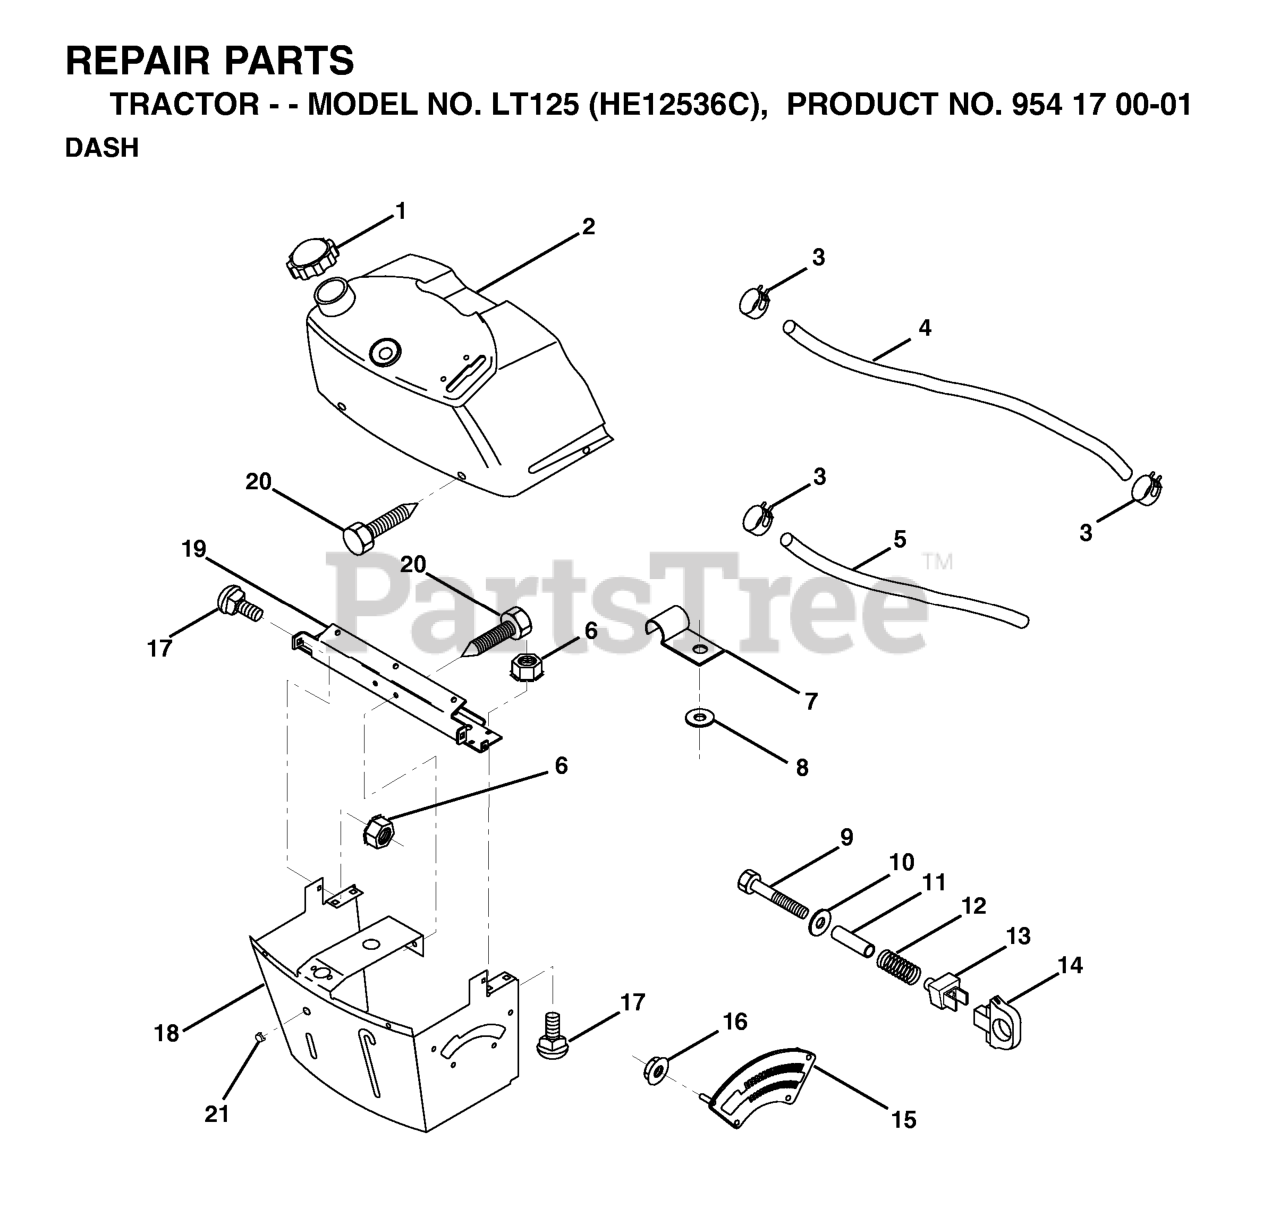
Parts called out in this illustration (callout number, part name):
1	CAP.FUEL.GREY
2	TANK ASM DASH LR
3	HOSE CLAMP
4	FUEL LINE
5	FUEL LINE T
6	Nut, Keps Blk Hex 1/4-20 UNC
7	CLIP T
8	WASHER PM
9	BOLT HEX FIN 1/4-20X1 3/4
10	WASHER
11	SPACER SPLIT
12	SPRING.COMPRESSION
13	KNOB HGT RETAINER
15	ADJUSTER QUAD
16	NUT.PUSH.3/16
18	SUPT ASSY DASH
19	CROSS BRACE
